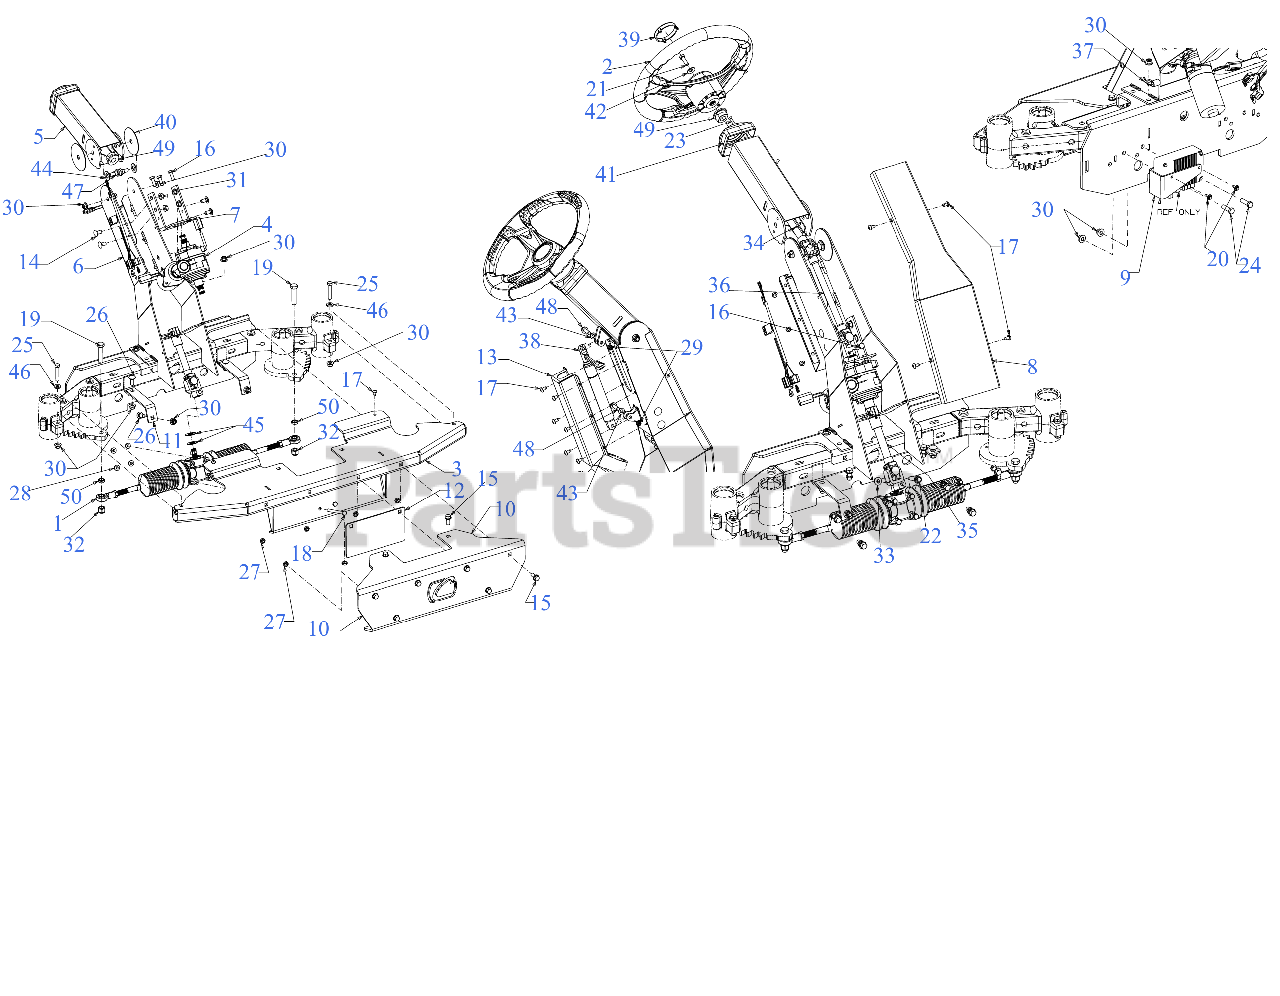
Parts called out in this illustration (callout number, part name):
1	STEERING GEARBOX
2	STEERING WHEEL
14	CARRIAGE BOLT 3/8-16 x .750 GR5
15	SCREW 3/8-16 x .875 GR5
16	SCREW M8-1.25 x 25 GR8.8
17	SCREW 1/4-20 x .5
18	SCREW 5/16-18 x 4.00 GR5
19	SCREW 1/2-20 x 2.25
20	SCREW M6-1 x .625
21	SCREW 5/16-18 x 1.00 GR5
22	HEX HEAD BOLT (3/8-16:1.50 GR8)
23	SCREW #10-16 x 1.25
24	SCREW 3/8-16 x 1.25 GR5
25	SCREW 3/8-16 x 2.0 GR5
26	CARRIAGE BOLT 3/8-16 x 1.00 GR5
27	JAM LOCK NUT
28	FLANGE LOCK NUT 5/16-18
29	FLANGE LOCK NUT
31	HEX LOCK NUT
32	HEX NUT 1/2-20 GR8 NYLON
33	LOCK NUT (3/8-16)
34	RETAINING RING .570 ID
35	STEERING SHAFT KIT
36	STEERING SHAFT TOP
37	J TYPE CLIP
38	TILT STEERING DAMPENING CYLINDER
39	STEERING WHEEL CAP
40	COLUMN PLATE
41	STEERING COLUMN COVER
42	BELL WASHER .337 X.867 x .057
43	FLAT WASHER .344 x .62
44	TEFLON WASHER .565X1.20
45	FLAT WASHER NYLON 5/8
46	FLAT WASHER
47	SHOULDER SCREW .498 DIA x .340
48	SHOULDER SCREW
49	FLANGE BEARING
